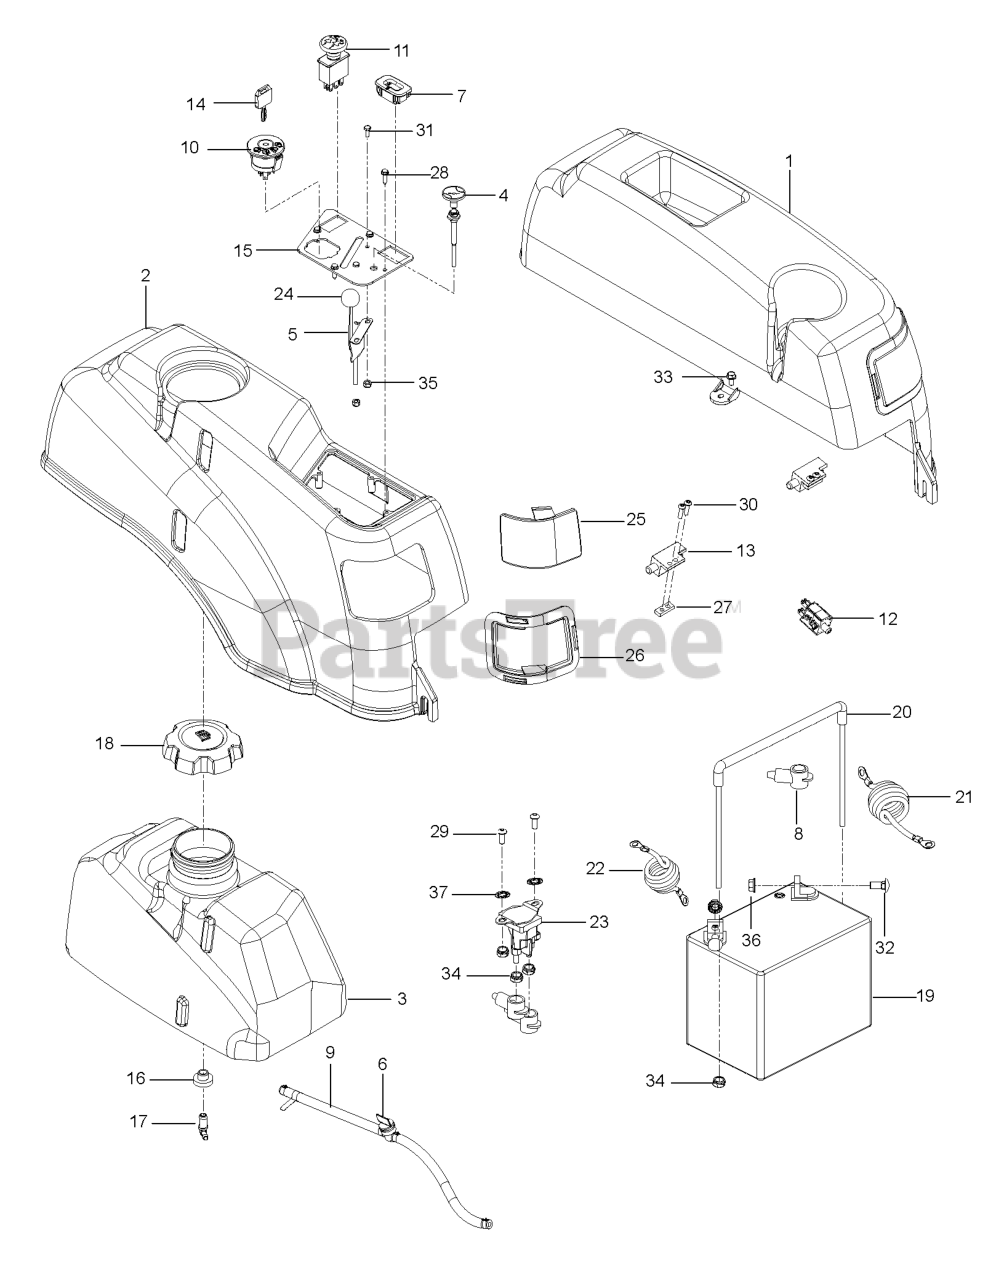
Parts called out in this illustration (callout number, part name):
1	FENDER, LT
2	RP.FENDER, RT
4	CONTROL-CHOKE 57"
5	THROTTLE CONTROL W/BALL KNOB
6	FUEL VALVE
7	HOUR METER
8	TERMINAL COVER-SM
9	FUEL LINE 5"
10	RP IGNITION SWITCH
11	RP.SWITCH, BLADE
12	SWITCH, BRAKE 3P
13	SWITCH, INTERLOCK
14	KEY
15	CONSOLE.PLATE.BLACK
16	RUBBER GROMMET
17	STEM, FUEL TANK
18	FUEL CAP, HTC
19	BATTERY, 12 V 330 AMP
20	BATTERY TIE DOWN ASSEMBLY
21	CABLE POSITIVE, LONG
22	BATTERY CABLE, NEGATIVE
24	KNOB.ROUND.BALL.BLACK
25	LENS, COLORED RIGHT
26	RT HEADLIGHT RIM GREY
27	TAPPED PLATE
28	SCR #10-12X3/4 HEX WAS HD ZD
29	SCREW #10 X 1/2 SELF TAPPING
30	SCR 1/4-20 X 5/8 BTN SKT HD ZD
31	HCS #10-24 X 1/2
32	BOLT 5/16C X 3/4" CARRIAGE
33	BOLT 1/4-20 X 1/2 HWST
34	NUT.1/4-20.HEX.NYLOC.ZD
35	NUT 10-24 NYLOC
36	5/16-18 NYLOC FLANGE NUT
37	WASHER 1/4 INT TOOTH
